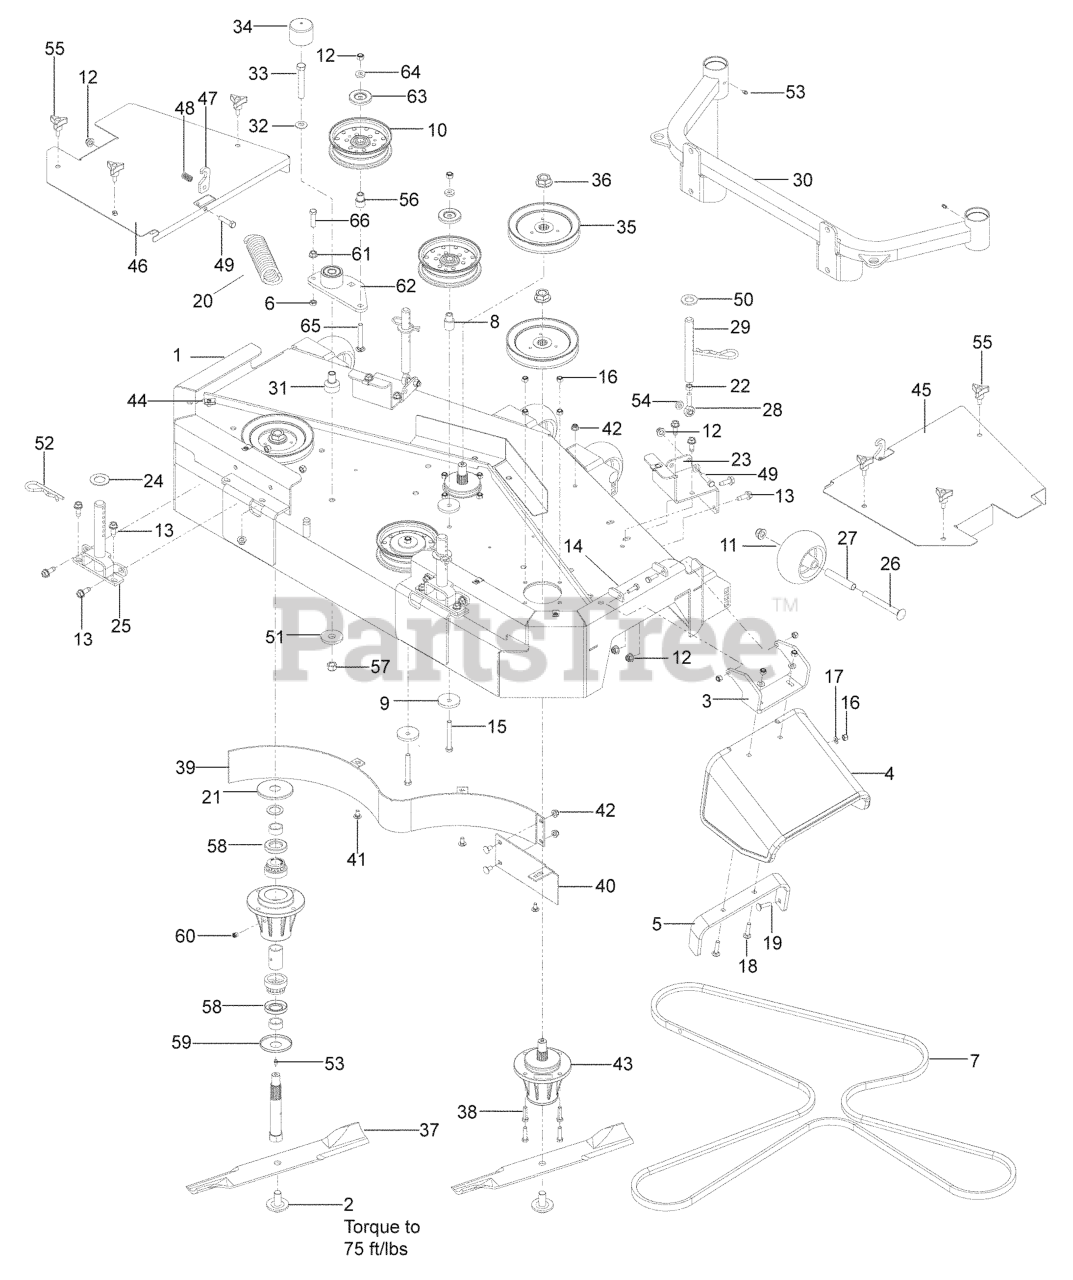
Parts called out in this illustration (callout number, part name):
1	CUTTER DECK w/DECALS
2	BLADE BOLT/WASHER
3	HINGE CHUTE - BLACK
4	CHUTE, RUBBER DISCHARGE WB
5	BRKT, REINF-CHUTE WB
6	NUT 3/8-16 HEX JAM
7	BELT, DECK
8	IDLER BUSHING
9	SPINDLE WASHER
10	IDLER PULLEY
11	ROLLER, GAUGE .635 BORN
12	NUT 3/8-16 HEX FLG NYLOC ZD
13	BOLT 3/8-16 X 1.0
14	HCS 5/16C X 1
15	HCS 3/8C X 3
16	NUT 5/16 NYLOC
17	FLAT WASHER 5/16 SAE
18	RHSNB 5/16-18 X 1-1/2 GR 5 ZD
19	BOLT, CARRIAGE 5/16X1-1/4
21	TOP DUST CAP
23	SUPPORT - FRONT, LH
26	RHSNB 1/2-13 X 4.75 GR5 ZD
27	TUBE, ROLLER AXLE
28	ROD END - 3/8-24 RH
30	SUPPORT, CASTER 52 OR
31	PIVOT, BEARING
32	CONTACT BELLSPR 1/2
33	HCS 1/2C X 3 1/4
34	CAP, VINYL
35	PULLEY - 6.57
36	NUT FLANGE 3/4-16
37	BLADE OEM 18"
38	HCS 5/16C X 1 1/4
39	MAIN BAFFLE 52"
40	CENTER BAFFLE - 52"
41	CARRIAGE BOLT 5/16C X 5/8"
42	5/16-18 NYLOC FLANGE NUT
43	HOUSING ASM, 72
44	U-CLIP 5/16-18 NUT RETAINER
45	COVER, 52 RH GY
46	COVER, 52 LH GY
48	SPRING - COMPRESSION
49	HCS 3/8C X 1 1/2
50	WASHER 3/4 FLAT SAE ZD
51	WASHER, SUPPORT
53	ZERK
54	WASHER 3/8 X 3/4 X .187 TK
55	KNOB W/STUD
56	BUSHING, IDLER
57	NUT 1/2-13 HEX NYLOC ZD
58	SHAFT SEAL
59	BOTTOM DUST CAP
60	PLUG-VENTED
61	NUT 3/8C WHIZ
62	ARM-IDLER W/BRG
63	DUST SHIELD
64	WASHER, 3/8 THICK
65	RHSNB 3/8-16 X 2.75
66	HCS 3/8-16 X 1-1/2
